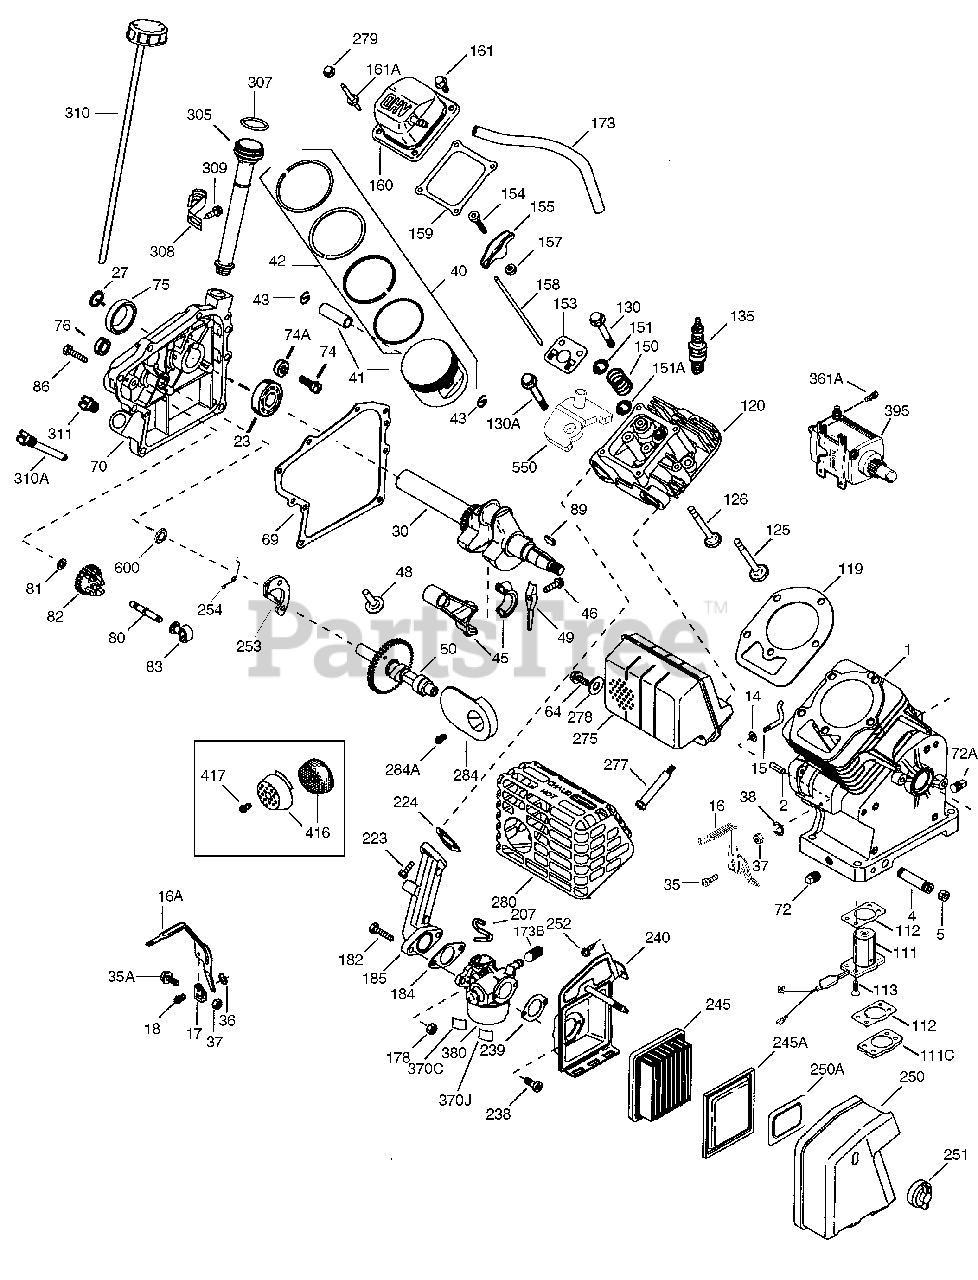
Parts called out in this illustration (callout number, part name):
1	"Cylinder (Incl. 2, 20 & 72)
2	Dowel Pin
14	Flat Washer
15	Governor Rod
16	Governor Lever
17	Governor Lever Clamp
18	Screw, Torx T-15, 8-32 x 3/8"
23	Ball Bearing
27	Bearing Retainer
30	Crankshaft
35	Screw, 10-32 x 3/4"
36	Lock Washer #8
37	Lock Nut, 10-32
38	Retaining Ring
40	Piston, Pin & Ring Set (Std.)
40	Piston, Pin & Ring Set (.010" OS)
41	Piston & Pin Ass'y (Std.) (Incl. 43)
41	Piston & Pin Ass'y (.010" OS) Incl. 4 3
42	Ring Set (Std.)
42	Ring Set (.010" OS)
43	Piston Pin Retaining Ring
45	Connecting Rod Ass'y (Incl. 46 & 49)
46	Connecting Rod Bolt
48	Valve Lifter
49	Oil Dipper
50	Camshaft (Incl. 150, 253 & 254)
64	Screw, 1/4-20 x 1-1/8"
69	* Cylinder Cover Gasket
70	Cylinder Cover Incl. 75 thru 83 & 311
72	Oil Drain Plug (Sq. hd., 1/4-18)
75	Oil Seal
80	Governor Shaft
82	Governor Gear Ass'y (Incl. 81)
83	Governor Spool
86	Screw, 1/4-20 x 1-1/4"
89	Flywheel Key (also available in Packa ged Part #740007B)
119	* Cylinder Head Gasket
120	Cylinder Head
125	Exhaust Valve (Std.) (Incl. 151)
125	Exhaust Valve (1/32" OS) (Incl. 151)
126	Exhaust Valve (1/32" OS) (Incl. 151)
126	Intake Valve (Std.) (Incl. 151 & 151A )
130	Screw, 5/16-18 x 1-1/2"
130A	Screw, 5/16-18 x 2-41/64"
135	Resistor Spark Plug (RN4C) also avail able in Packaged Part #740069
150	Valve Spring
151	Valve Spring Cap
153	Push Rod Guide
154	Rocker Arm Stud
155	Rocker Arm
157	Nut, 1/4-28
158	Push Rod
159	* Rocker Arm Cover Gasket
160	Rocker Arm Cover
173	Breather Tube
182	Screw, 1/4-20 x 1"
184	* Carburetor To Intake Pipe Gasket
185	Intake Pipe
207	Throttle Link
224	* Intake Pipe Gasket
229	Nut, 1/4-20
229	Nut & Lock Washer
238	Screw, 10-32 x 1/2"
239	* Air Cleaner Gasket
240	Air Cleaner Body (Incl. 239)
245	Air Filter (Paper) (also available in Packaged Part #740031B for model VLV only) (also available in Packaged Pa rt #740061C for model OH195)
245A	Poly Pre-Filter (also available in Pa ckaged Part #740061C)
250	Air Filter Cover (Incl. 250A)
250A	Air Filter Baffle
251	Wing Nut
253	Compression Release Weight
254	Compression Release Spring
275	Muffler
277	Screw, 1/4-20 x 2-9/32"
280	Heat Shield
305	Oil Fill Tube
307	"O" Ring
308	Oil Fill Tube Clip
310	Dipstick
311	Oil Fill Plug (Incl. 312) also availa ble in Packaged Part #740079
338	Screw, 10-32 x 1/2"
370	Decal - Tecumseh Logo for Top of Reco il Starter
380	Carburetor (Incl. 184)
416	Spark Arrestor Kit (Incl. 417) Option al
999	Summer Maintenance Kit (incl. Oil, Sp ark Plug, Air Cleaner, & Ultra Fresh)
